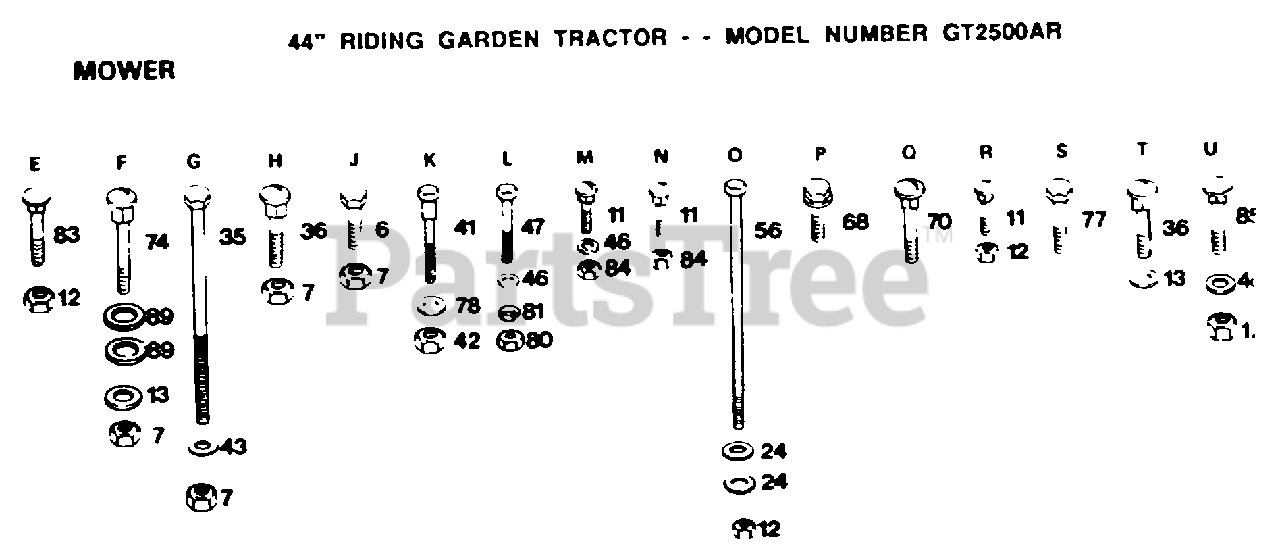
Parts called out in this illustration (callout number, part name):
11	BOLT
13	WASHER
24	WASHER M
35	BOLT - HEX 3/8 - 16 X 3
41	BOLT SHOULDER
42	LOCKNUT
43	WASHER
46	WASHER
56	BOLT
68	SCREW
70	No Desciption for Part
74	BOLT
77	BOLT
78	WASHER
80	NUT.HEX.5/16-18
81	LOCKWASHER
83	BOLT
89	WASHER
